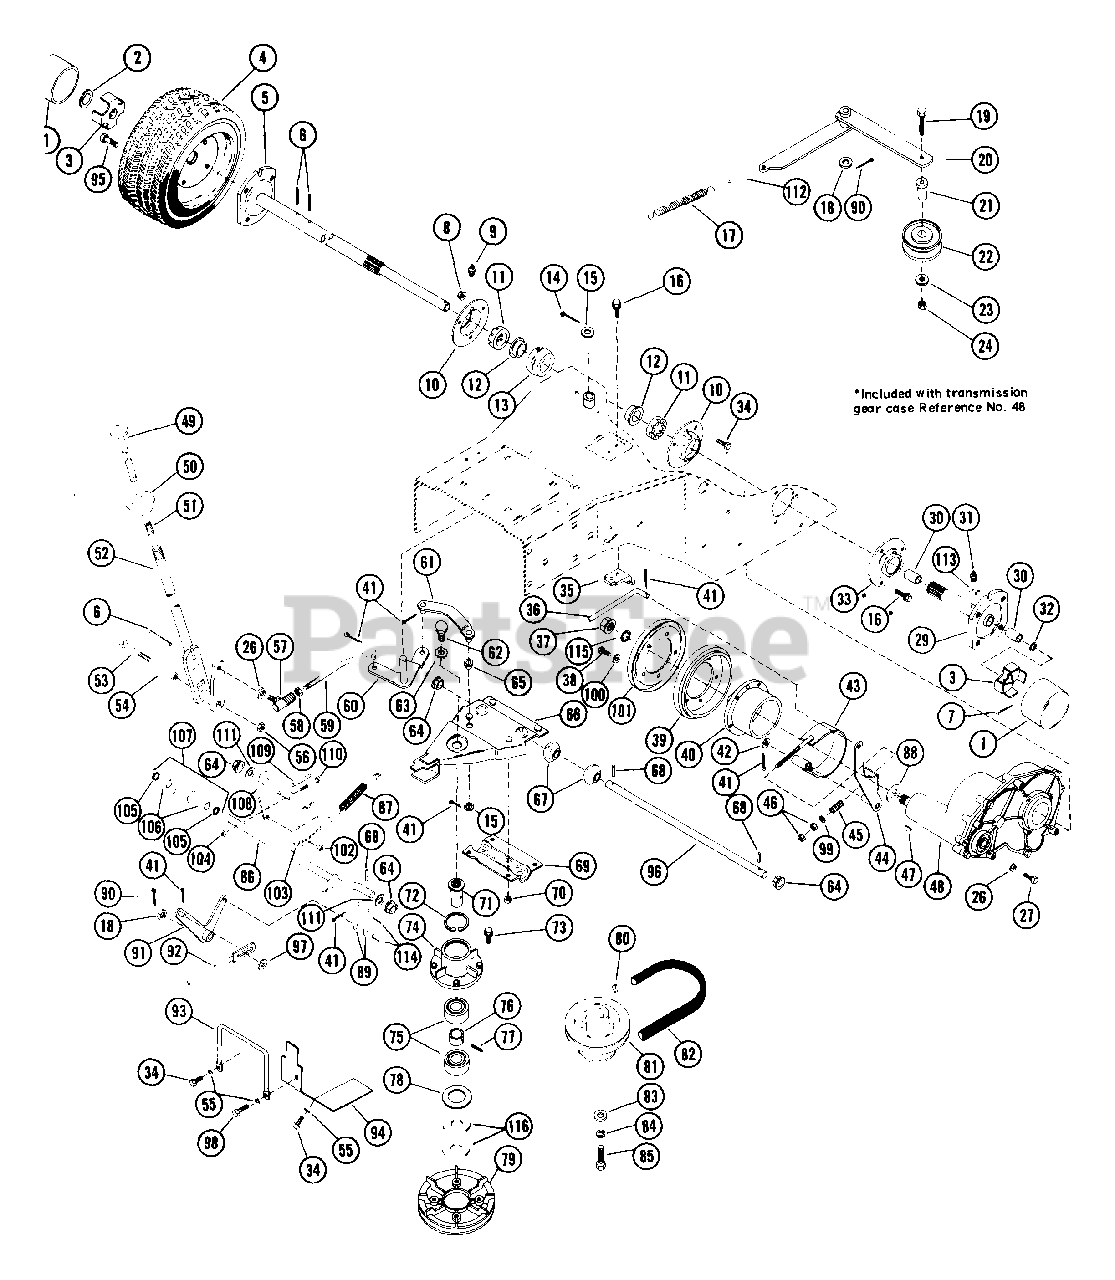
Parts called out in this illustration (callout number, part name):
1	HUB CAP
2	PUSHNUT
3	SPINDLE CUP
4	TERRA TIRE & WHEEL ASSEMBLY
5	R H AXLE SHAFT
6	PIN-ROLL .188X1.50
7	PIN-COTR .12 X 1.25 PL
8	NUT-LK-FLG .250-20 PL
9	ZERK FITTING
10	BEARING FLANGE
11	ADJUSTMENT SPACER
12	BSHG-FLG 1.125X1.31X.50X1.62BR
13	SPHERICAL BUSHING
14	PIN-COTR .12X1.0 PL
15	WSHR-FL-STL .505X.880X.072 PL
16	BLT-SCRHFWH .25-20X.62 PL
17	SG-TENS 4.75 FREE LENGTH
18	WSHR-FL-STL .505X1.000X.062
19	BLT-HEX .31-18X1.25 PL GR2
21	SPCR, BRG .315X.50X.688X.281
22	IDLER
23	WSHR-FL-STL .38X.875X.083 PL
24	NUT-LK .312-18 GR A PL
26	WSHR-LK .312X.097 PL HVY
27	BLT-HEX .31-18X1.50 PL GR2
29	L H AXLE ASSEMBLY
30	BSHG-SLV .750X.814X .750 BRZ
31	SPIN DRIVE ZERK FITTING
32	O-RING .755X.950X.097
33	SEAL 1.125X2.496X.380
34	BLT-HEX .25-20X.50 PL GR2
35	NEUTRAL STOP
36	BRAKE ROD
37	NUT-LK-NYL.625-18 PL
38	BLT-HEX .31-18X.50 PL GR2
39	FRICTION DISC
40	FRICTION DISC HUB
41	PIN-COTR .09X.75 PL
42	WSHR-FL-STL .380X.626X.033
43	BRAKE BAND
44	BRAKE LEVER
45	SG-COMP .105X.585X.75
46	NUT-HEX .312-18
47	KEY-WDRF .188X.875X.375 SAE11
48	GEAR CASE ASSEMBLY
49	SHIFT CONTROL ROD
50	SHIFT BALL
51	SG-COMP ??X.44X?? WLD 10
52	SHIFT LEVER
53	BLT-HEX .38-16X2.50 PL GR2
54	SHIFT SPACER
55	WSHR-LK .250X.077 HVY PL
56	NUT-LK-CTR .375-16 GR A PL
57	SNAP IN BALL JOINT
58	NUT-HEX .312-24 PL
59	SHIFT ROD
60	SHIFT LEVER
61	SHIFT LINK
62	SPINDLE STUD
63	WSHR-LK-EXT .500X.040 MED
64	FLANGE BUSHING
65	BSHG-FLG .372X.500X.312X.625NY
66	MTG PLATE
67	BEARING
68	PIN-ROLL .188X1.13
69	BEARING RETAINER
70	NUT-LK-CTR .250-20 PL
71	SPINDLE
72	SNAP RING KIT
73	BLT-SERHFWH .25-20X.75 PL
74	SPINDLE HOUSING
75	BRG-BALL .751X1.78X.61
76	SPACER .753X1.000X.457
77	PIN-ROLL .188X1.00
78	WSHR-FL-STL 1.375X2.125X.075
80	KEY-STR .25X2.0X.25
81	SHEAVE
82	V-BELT, SAE 380-RAW EDGE
83	WSHR-FL-STL .438X1.125X.19
84	WSHR-LK .375X.115 HVY PL
85	BLT-HEX .38-24X1.25 BLKO GR5
87	SG-COMP .062X.438X6.625
88	WSHR-FL-STL .627X.990X.032
89	LINK PLATE
90	PIN-COTR .09X1.0 PL
91	CLUTCH LEVER
92	CLUTCH ROD
93	BELT GUIDE
94	SPLASH GUARD
95	BLT-WHL .50-20X.75 GR5 PL
96	HINGE SHAFT
97	WSHR-FL-STL .382X.812X.023 PL
98	BLT-HEX .25-20X.75 PL GR2
99	WSHR-FL-STL .323X.625X.062 PL
100	WSHR-LK-INT .313X.030 PL
102	NUT-KEPS 8-32
103	STOP ADJUSTMENT
104	NUT-LK TOP .250-20 PL
105	SEAL .625X.875X.125
106	BSHG-SLV .625X.750X.500 BR
107	ROLLER ASSEMBLY
109	PIN-GRV .250X1.25 TP A
110	BLT-HEX .25-20X1.50
111	WSHR-FL-STL .630X1.005X.062 PL
112	SPRING HOOK
113	WSHR-LK .250X.047 LT PL
114	CLEVIS PIN
115	WSHR-LK-INT .625X.045 PL
116	WSHR-FL-STL 2.125X1.375X.005
